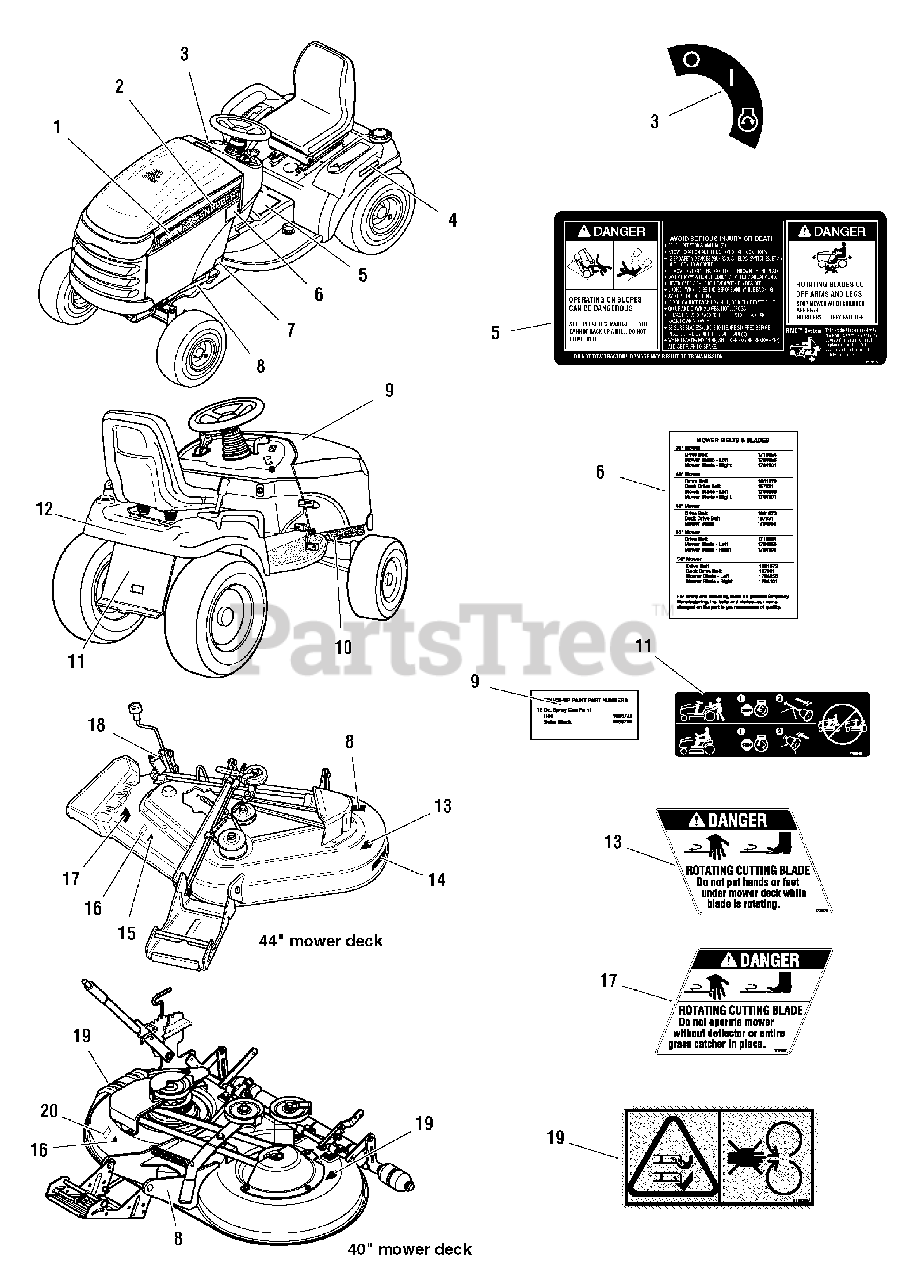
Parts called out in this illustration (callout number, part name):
1	DECAL, LT1840
1	DECAL, LT2044
2	DECAL, Hood Stripe, Snapper, LH
2	DECAL, Hood Stripe, Snapper, RH
3	DECAL, Ignition Switch Symbols, White/Black
4	DECAL, Automatic Control Traction
5	DECAL, Tunnel Cover, Danger Slopes/Blades
6	DECAL, Drive Belts & Mower Blades
7	DECAL, Protective Sticker
8	* DECAL, I.D. Plate
9	DECAL, Touch Up Paint
10	* DECAL, Patent
11	DECAL, Transmission Release Valve
12	DECAL, Snapper
13	DECAL, Danger Do Not Put Hands/Feet in Mower
14	DECAL, Free Floating Mower, Silver
15	* DECAL, OPEI Certified
16	DECAL, 44", Silver on Black with Stripe
17	DECAL, Danger Do Not Operate Without Deflector
18	DECAL, Height of Cut, 38" & 44"
19	DECAL, Danger Rotating Blades
20	DECAL, 40", Silver on Black with Stripe
